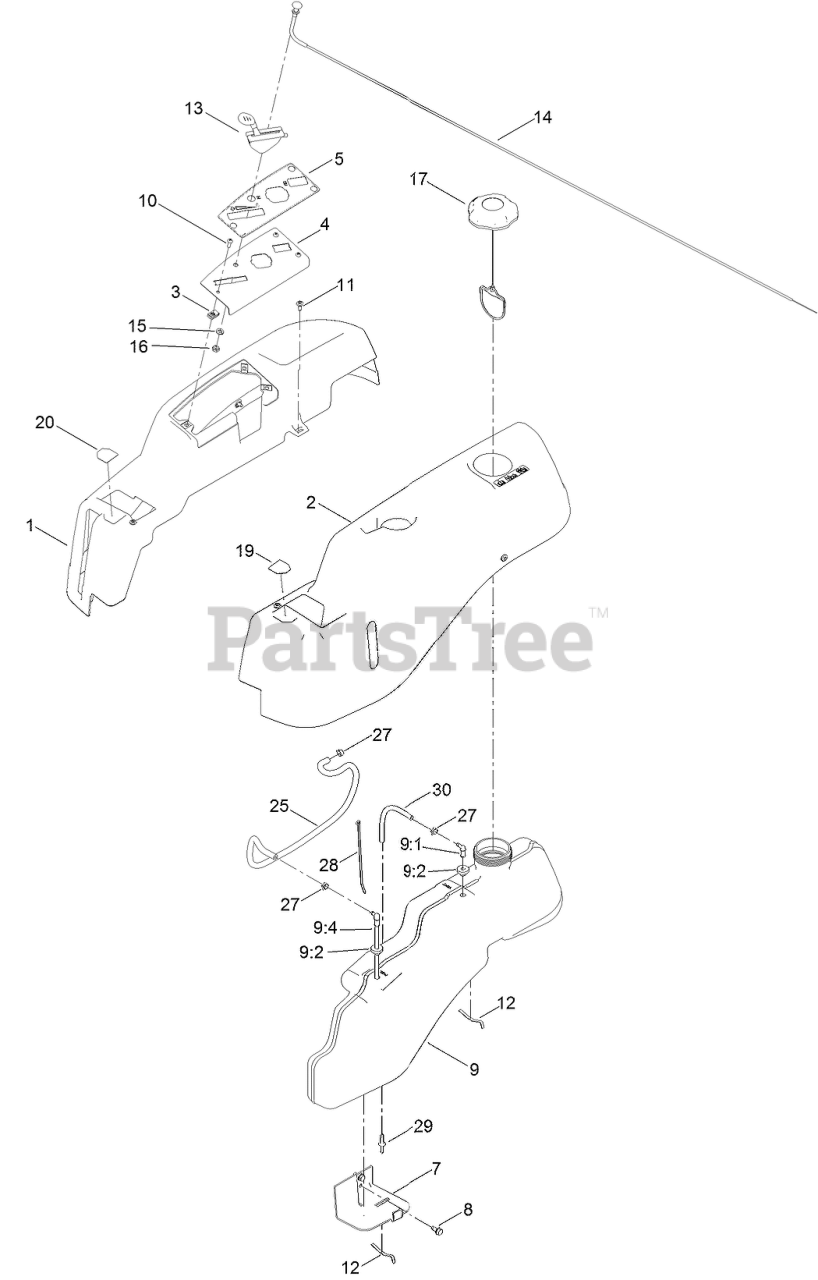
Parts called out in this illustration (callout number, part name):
1	POD-RH
2	POD-LH
4	PLATE-CONTROL
5	DECAL-PANEL, CONTROL
7	SUPPORT-TANK, FRONT
8	SCREW-HWHTF
9	FUEL TANK ASM
9:1	CONNECTOR-ELBOW, 90 DEG
9:2	BUSHING
9:4	FITTING-PLASTIC
10	SCREW-PRH
11	SCREW-SHOULDER
12	SPRING
13	CABLE-THROTTLE
14	CABLE-CHOKE
15	WASHER-LOCK
16	NUT-HEX JAM
17	CAP-FUEL, RATCHETING
19	DECAL-LEVER, CONTROL (LH)
20	DECAL-LEVER, CONTROL (RH)
25	HOSE-FUEL
27	CLAMP-HOSE
28	TIE-CABLE
29	ADAPTOR-ORIFICE
30	HOSE-FUEL
